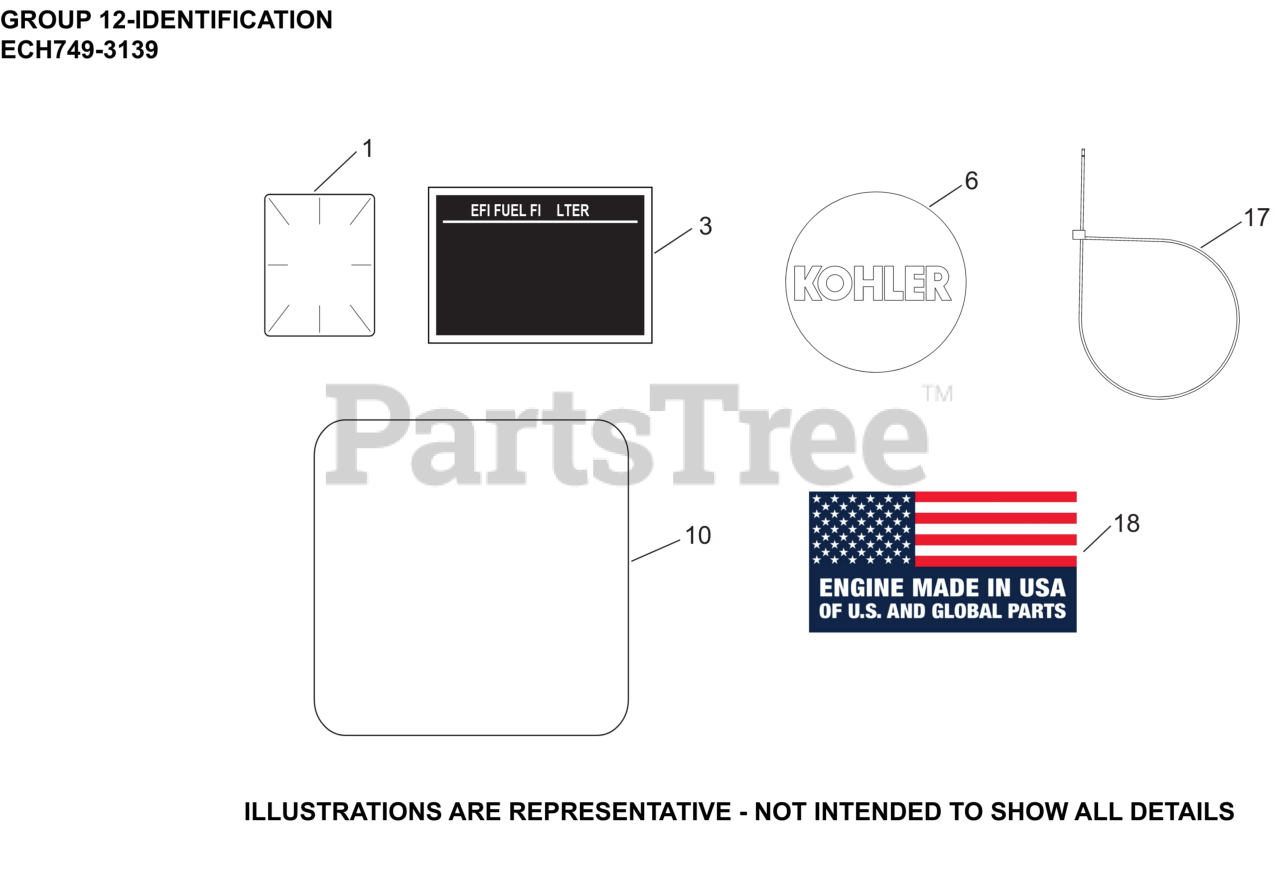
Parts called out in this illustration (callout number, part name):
1	LABEL, CLEAR LAMINATION
3	LABEL, EFI FUEL FILTER
6	LABEL, GRASS SCREEN
10	DECAL, HDAC 26.5 HP/747cc/ECV-ECH749
18	DECAL, USA
